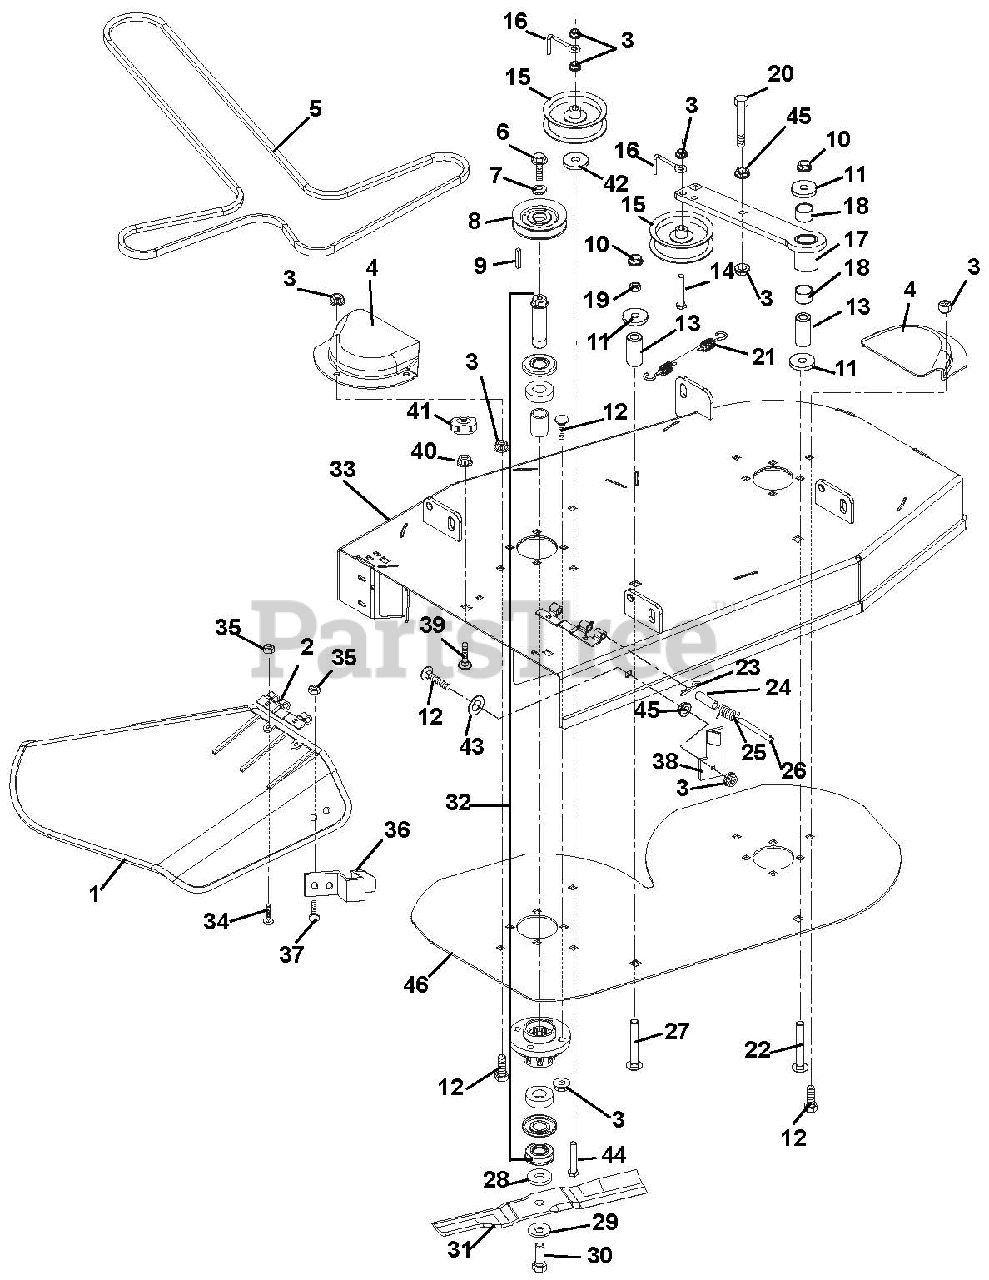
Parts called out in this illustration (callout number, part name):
1	Discharge Chute
2	Hinge, Plate
3	Nut, 3/8-16 Flange Nyloc
4	Belt Cover
5	V-Belt, HA x 97
6	Bolt, Hex .38-16 x 1.00 Grade 8 w/Epoxy Patch
7	Washer, Flat Steel .406 x 1.50 x .245
9	Key, Square .25 x .38 x .25
10	Nut, Locking Top Flange .50-13
11	Washer, Flat Steel .515 x .625 x .250
12	Bolt, Round Head Square Neck .38-16 x 1.25
14	Bolt, Hex .38-16 x 2.50
15	Idler Flanged 3.50
16	Finger Belt
17	Weldment, Idler Pivot Arm
18	Bearing, 1.00 x 1.12 x .75
19	Nut, Spinlock Flange .50-13
20	Bolt, Hex .38-16 x 2.00
21	Spring, Tension .187 x 1.50 x 9.94
22	Bolt, Round Head Square Neck .50-13 x 3.50
23	Pin, Hair Internal .08 x .18 x 1.18
24	Bushing, Sleeve
25	Spring, Torsion .095 x .50 x 1.00
26	Pin, Clevis
27	Bolt, Round Head Square Neck .50-13 x 3.75
28	Washer, Flat .688 x 1.75 x .134
29	Washer, Beveled .63 x 1.625 x .140
30	Bolt, Hex .62-18 x 1.75 Grade 8
31	Blade, Mower
32	Assembly, Spindle
33	34" Zoom/ZT Deck
34	Bolt, Round Head Square Neck .25-20 x .75 Grade 5
35	Nut, Locking Top Flange .25-20
36	Flat Spring
37	Bolt, Round Head Square Neck .25-20 x .50 Grade 5
38	Bracket, Chute Lock
39	Bolt, Round Head Square Neck .31-18 x 1.00
40	Nut, Spinlock Flange .312-18
41	Knob, Clamping
42	Spacer, .39 x 1.50 x .380
43	Washer, Flat Steel .563 x 1.38 x .109
44	Bolt, Round Head Square Neck .38-18 x 2.75 Grade 5
45	Nut, Spinlock Flange .375-16
46	Plate, 34" Doubler
